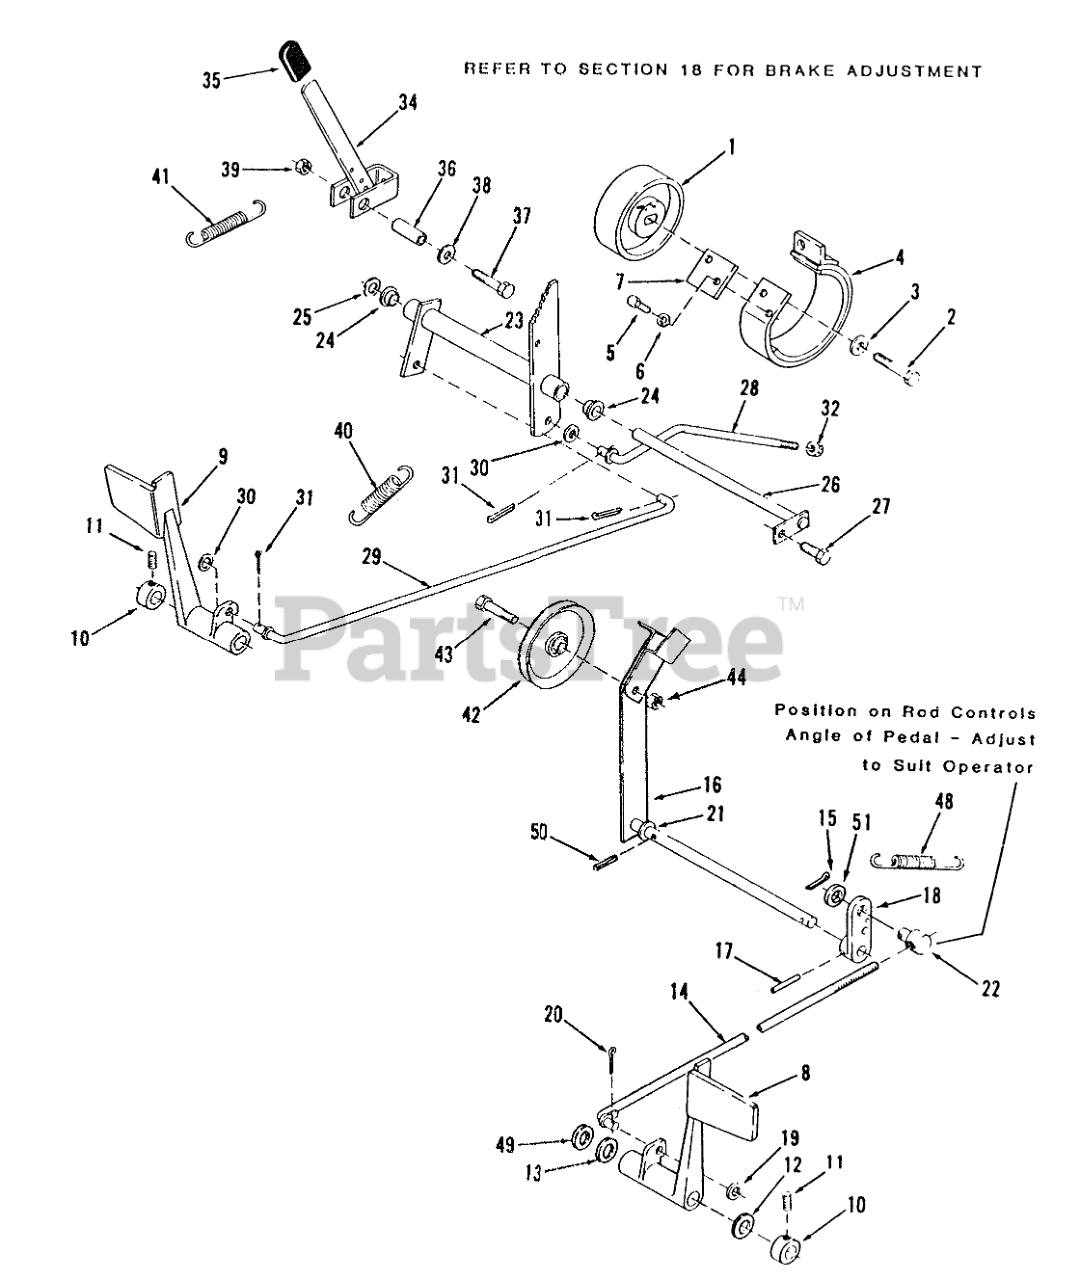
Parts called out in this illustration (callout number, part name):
1	DRUM-BRAKE
2	SCREW-HEX HD CAP
3	WASHER
4	BRAKE BAND ASM
5	H H C S
6	Washer
7	Plate-Stop
8	Pedal-Clutch
9	Pedal Brake
10	Collar
11	SCREW-SET
12	WASHER-BOWED
13	WASHER
14	ROD AND GUIDE ASM
15	Cotter Pin
16	ASSY-IDLER ARM R
17	PIN-SPIROL
18	Arm-Clutch Rod
19	WASHER-NYLON
20	Pop Rivet
21	SHIM-WASHER
22	TRUNNION
23	Bellcrank Assy
24	BUSHING-FLANGED
25	Washer
26	ROD ASM
27	SCREW
28	ROD-REAR BRAKE
30	WASHER-NYLON
31	Pop Rivet
32	NUT
34	ASSY-BRAKE LEVER WAB
35	GRIP
36	SPACER
37	Bolt
38	Washer
39	LOCKNUT-FLANGE
40	SPRING-BRAKE
41	SPRING-EXTENSION
42	PULLEY-IDLER
43	BOLT-SPECIAL HEX
44	Nut
48	SPRING-CLUTCH
49	Washer
50	PIN-SPIROL
51	Washer
